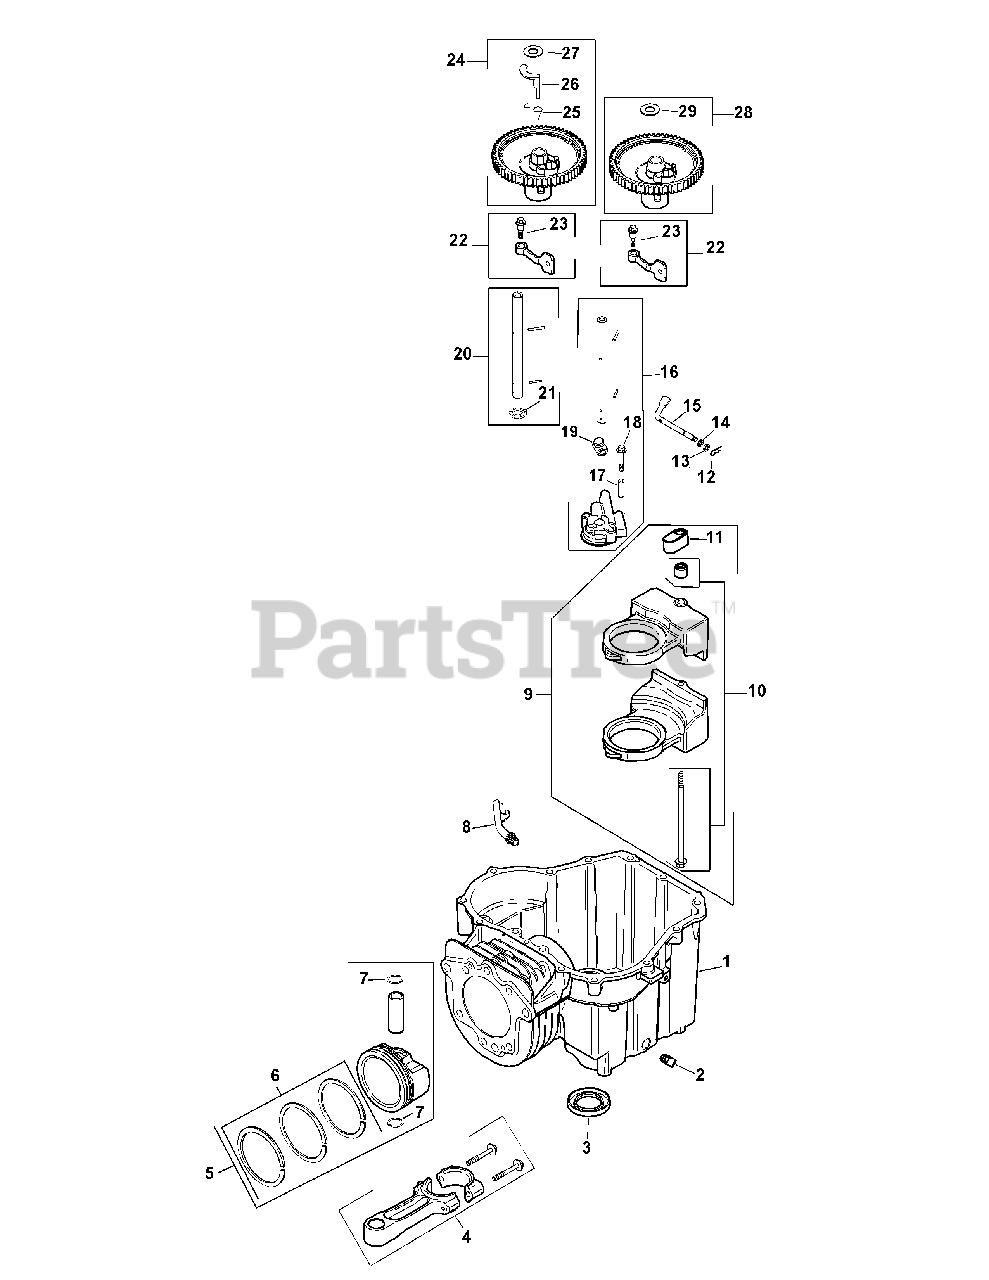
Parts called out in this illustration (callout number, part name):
1	Crankcase (Use Short Block KH-20-522-05)
2	Square Head Pipe Plug, 3.8
3	Oil Seal
4	Connecting Rod
5	Piston w/ Ring Set (Inc. 6 & 7)
6	Ring Set (94 Mm)
7	Piston Pin Retainer
8	Drain Back Tube
9	Balance Weight Kit (Inc. 10 & 11)
10	Screw/Guide Pin Kit
12	Hitch Pin Clip
13	Flat Washer, 6 mm
15	Governor Cross Shaft
16	Oil Pump Assy. (Inc. 17, 18 & KH-20-041-01-S)
17	Oil Pump Screw Spacer
18	Oil Pump Screw
19	Cam Shaft Center . Exhaust (Inc. 20)
20	Thrust Washer
21	Cam Lever Assembly (Inc. 22)
22	Shoulder Screw, M6 x 1.0 x 26
23	Cam Gear Assembly . Exhaust (Inc. 24-26)
25	ACR Weight
26	ACR Thrust Washer
27	Cam Gear Assembly . Intake
